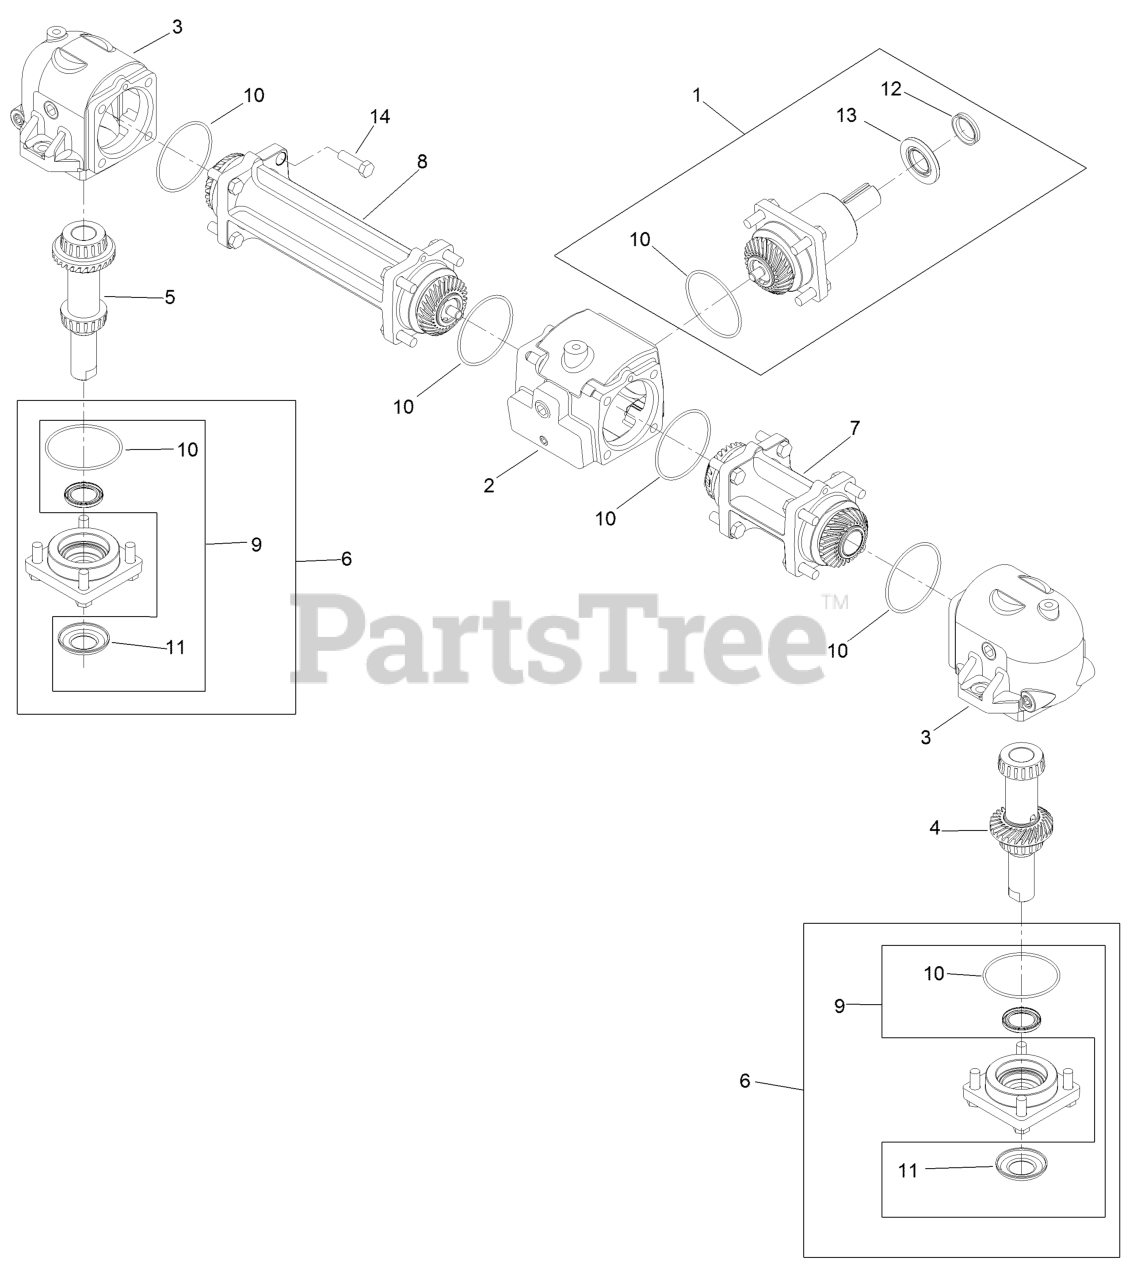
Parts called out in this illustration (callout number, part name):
1	INPUT PINION ASM
2	HOUSING-CENTER
3	HOUSING-END
4	LH OUTPUT SHAFT AND GEAR
5	RH OUTPUT SHAFT AND GEAR
6	CAP-OUTPUT
7	TUBE-CONNECTOR, SHORT
8	TUBE-CONNECTOR, LONG
9	OUTPUT SEAL KIT
10	SEAL-O-RING
11	WASHER-CUPPED
12	SEAL-V-RING
13	SEAL-INPUT
